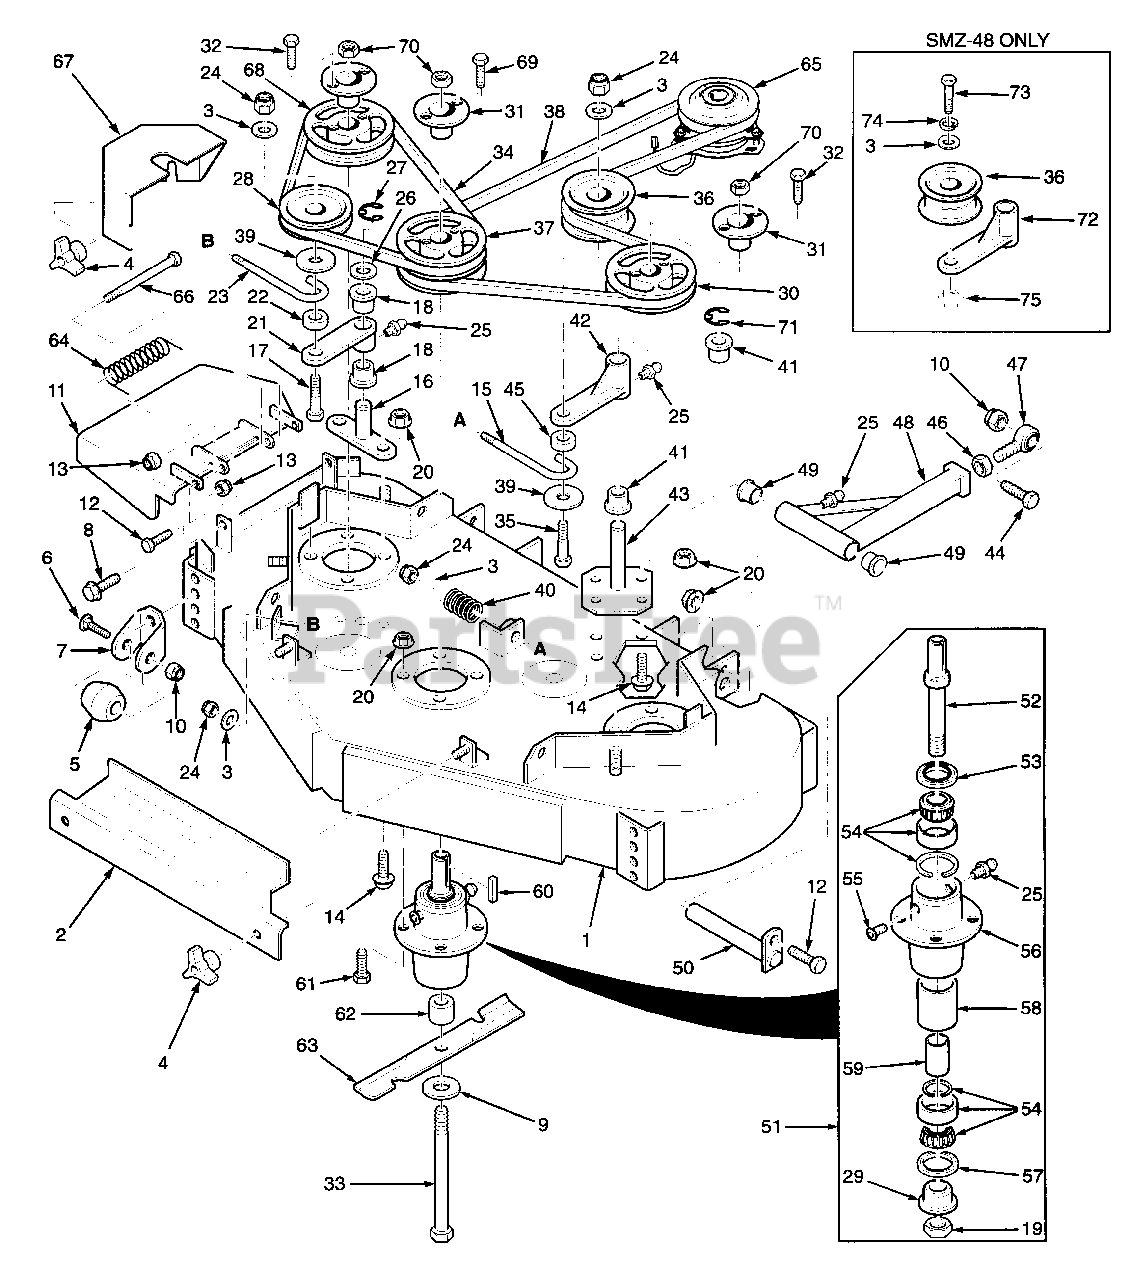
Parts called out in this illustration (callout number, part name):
1	Cutter Deck
2	Belt Cover, Front
3	Flatwasher, 3/8" Spcl. (.391 x .938 x .105)
4	Wing Nut, 3/8-16
5	Anti-Scalp Wheel
6	Bolt, carriage 3/8-16 x 4"
7	Anti-Scalp Wheel Bracket
8	Bolt, Hex Serrated Flange 3/8-16 x 1"
9	Flatwasher, 5/8" (.688 x 1.75 x .134)
10	Nut, Lock 3/8-16 Center Lock
11	Discharge Chute
12	Bolt, Hex Head 5/16-18 x 1"
13	Nut, Hex Elastic Stop 5/16-18
14	Bolt, Hex Serrated Flange 5/16-18 x 3/4"
15	"J" Rod
16	Idler Pivot Base
17	Bolt, Hex Head 3/8-16 x 2-1/4"
18	Bushing
19	Nut, Special 1-1/16-18
20	Nut, Hex Serrated Flange 5/16-18
21	Idler Arm
22	Spacer
23	"J" Rod
24	Nut, Hex Elastic Stop 3/8-16
25	Grease Fitting
26	Flatwasher, 3/4"
27	Ring, Retaining 3/4" External "E"
28	Pulley, Idler
29	Spindle Bushing, Bottom
30	Pulley, LH Spindle
31	Tapered Hub, 1-1/8 Bore
32	Bolt, Hex Head 1/4-20 x 3/4"
33	Bolt, Hex Head 5/8-11 x 9-1/2"
34	Belt, RH Blade Drive
35	Bolt, Hex Head 3/8-16 x 4-1/2"
36	Pulley, Idler Cutter Engagement
37	Pulley, Double Groove
38	Belt, Blade Drive
39	Flatwasher, 3/8" (.375 x 1.5 x .06)
40	Spring, Idler Tension
41	Bushing
42	Idler Arm
43	Idler Pivot Base
44	Bolt, Hex Head 5/8-11 x 3"
45	Spacer
46	Nut, Hex 5/8-18 UNF
47	Rod End
48	Push Arm
49	Bushing
50	Push Arm Shaft
51	Spindle Assembly
52	Spindle Shaft
53	Seal, Top
54	Bearing Assembly
55	Relief Fitting, Tapered Spindle
56	Spindle Housing
57	Seal, Bottom
58	Spacer, Outside
59	Spacer, Inside
60	Key, 1/4 x 1/4 x 2"
61	Bolt, Hex Head 5/16-18 x 1-1/4"
62	Spacer, Tapered Spindle
63	Cutter Blade, 21" Standard
64	Spring, Discharge Chute
65	Electric Clutch
66	Bolt, Hex Head 5/16-18 x 4.25"
67	Belt Cover, LH
68	Pulley, RH Spindle
69	Bolt, Hex Head 1/4-20 x 1.375 Full Thread
70	Hex 5/8-11 UNC
71	Ring, Retaining 1-1/8" External "E"
72	Idler Arm
75	Nut, 3/8-16 Special W/Washer
